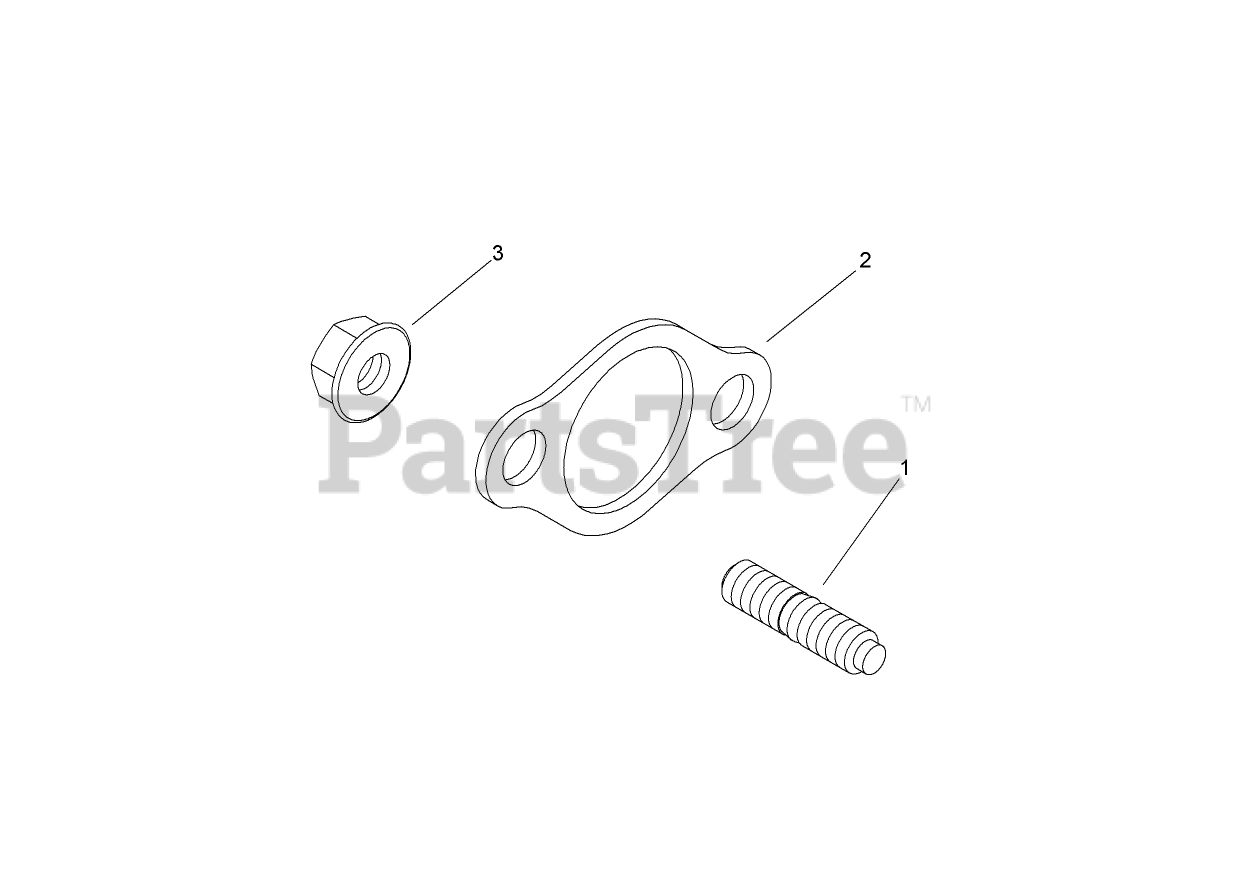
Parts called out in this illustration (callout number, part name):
1	STUD (M8X1.25X33)
2	GASKET-EXHAUST
3	NUT-FLANGE (M8X1.25)
